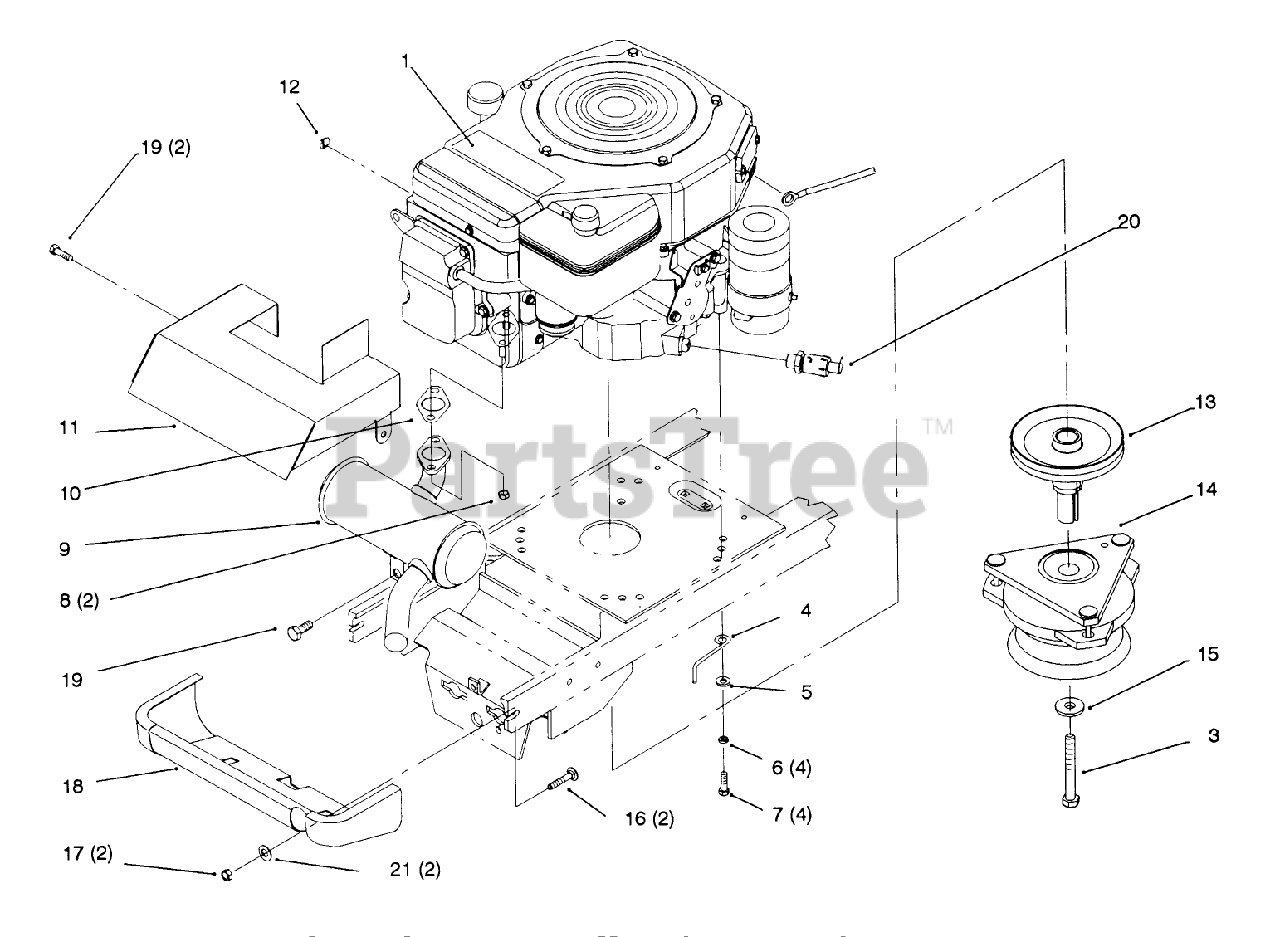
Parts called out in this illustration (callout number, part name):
1	DECAL - ENGINE
3	HHCS-M10X1.5X110 ESL
4	GUIDE-BELT
5	WASHER-PLAIN
6	WASHER-LOCK
10	KOHLER 12-041-03
11	SHIELD-MUFFLER
12	CLIP-RETAINER, WIRE
13	PULLEY-ENGINE
13	PULLEY- ENGINE GEAR
14	CLUTCH - ELEC PTO
15	WASHER
16	SCREW-CARR
17	NUT-LOCK, NI
19	SCREW
20	VALVE-DRAIN, OIL
21	WASHER-FLAT
